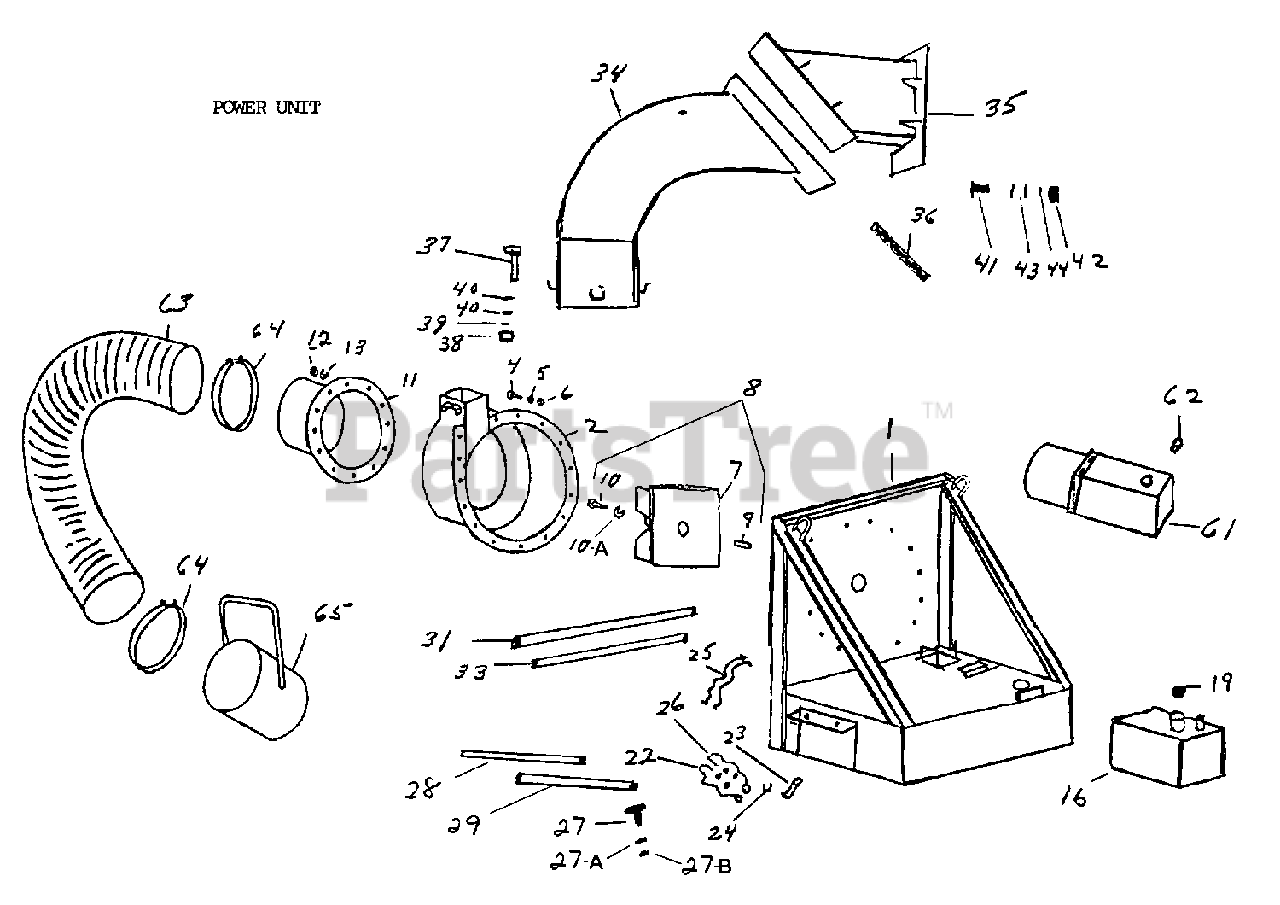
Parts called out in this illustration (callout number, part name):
1	Loader base
2	Blower housing
2	Blower housing (complete w/bolt-in wear liner)
4	3/8-16 x 1 hex bolt
5	3/8 lockwasher
6	3/8-16 hex nut
7	Impeller 20"
7	Impeller 25"
8	5/8-18 x 2 impeller bolt & key group
9	Impeller key
10	5/8 x 2 impeller bolt
11	16 intake flange
12	1/2 hex nut
13	1/2 lock washer
16	Fuel tank
17	Fuel tank strap
19	Fuel cap – specify ‘gas’
22	Valve assembly
23	Valve handle
24	Valve handle holder
26	Replacement micro switch for valve assembly
27	1/4-20 x 1-1/4 hex bolt (valve assembly mount)
27A	1/4 lock washer
27B	1/4-20 hex nut
28	Hydraulic hose – 1/2 x 23 – valve to jack
29	Hydraulic hose – 1/2 x 43 – valve to jack
31	Hydraulic hose – 1/2 x 63 – valve to hyd. power unit
33	Hydraulic hose – 1/2 x 49 – valve to hyd. power unit
34	Stack & elbow assembly (with wear liner)
35	Discharge stack – leaf box side
36	Discharge stack gasket set
37	1/2 x 4-1/2 hex bolt
37	1/2 x 1-3/4 hex bolt
38	1/2 hex nut
39	1/2 lock washer
40	1/2 flat washer
41	3/8-16 x 1-1/4 hex bolt
42	3/8-16 hex nut
43	3/8 flat washer
44	3/8 lock washer
61	Hydraulic pump (power unit)
62	Breather cap
63	Intake hose – 12 x 10’
63	Intake hose – 16 x 7’ blue
64	12 hose clamp
64	16 hose clamp
65	12 intake nozzle
65	16 intake nozzle
